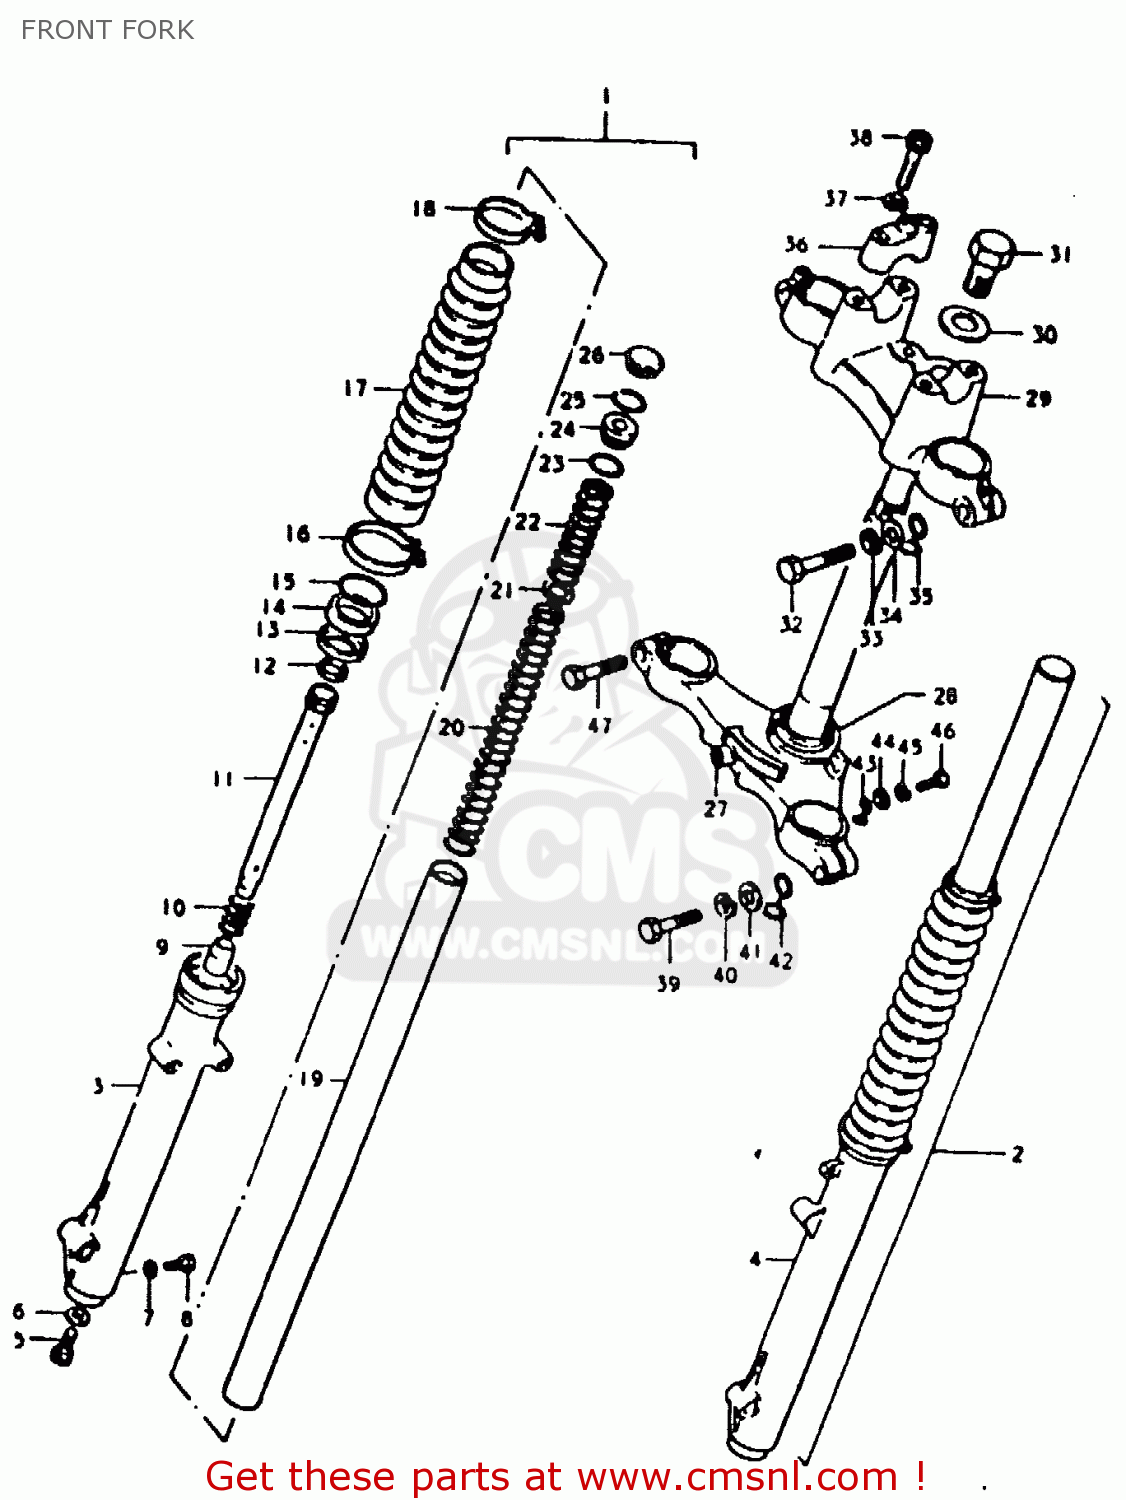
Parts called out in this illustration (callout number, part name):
1	DAMPER ASSY, RH
2	DAMPER ASSY, LH
3	TUBE,FORK,OUTER,RIGHT
4	TUBE,FORK,LEFT,OUTER
5	BOLT(8X27)
6	GASKET (NAS)
7	GASKET,DRAIN,PLUG (NAS)
8	BOLT(6X8)
9	PIECE,OIL LOCK
10	SPRING,REBOUND
11	CYLINDER
12	RING,PISTON
13	WASHER,FRONT FORK OIL SEAL
14	OIL SEAL,FRONT FORK
15	CIRCLIP,FORK OIL SEAL
16	CLAMP
17	BOOT
18	BAND
19	TUBE,FORK,INNER
20	SPRING,FRONT FORK
21	SEAT,SPRING
22	SPRING,FRONT FORK
23	O RING
24	SEAT,SPRING
25	RING,STOPPER
26	CAP,FRONT FORK
27	STEM,STEERING
28	RACE,STEERING OUTER LWR
29	HEAD,STEERING STEM
30	WASHER(10.5X30X2.3)
31	BOLT
32	BOLT
33	LOCK WASHER
34	WASHER
35	CLIP
36	HOLDER,HANDLEBAR
37	LOCK WASHER
38	BOLT 8X35
39	BOLT
40	WASHER,LOCK 12
41	WASHER
42	CLIP
43	CLIP
44	WASHER
45	LOCK WASHER
46	SCREW 6X12
47	BOLT
